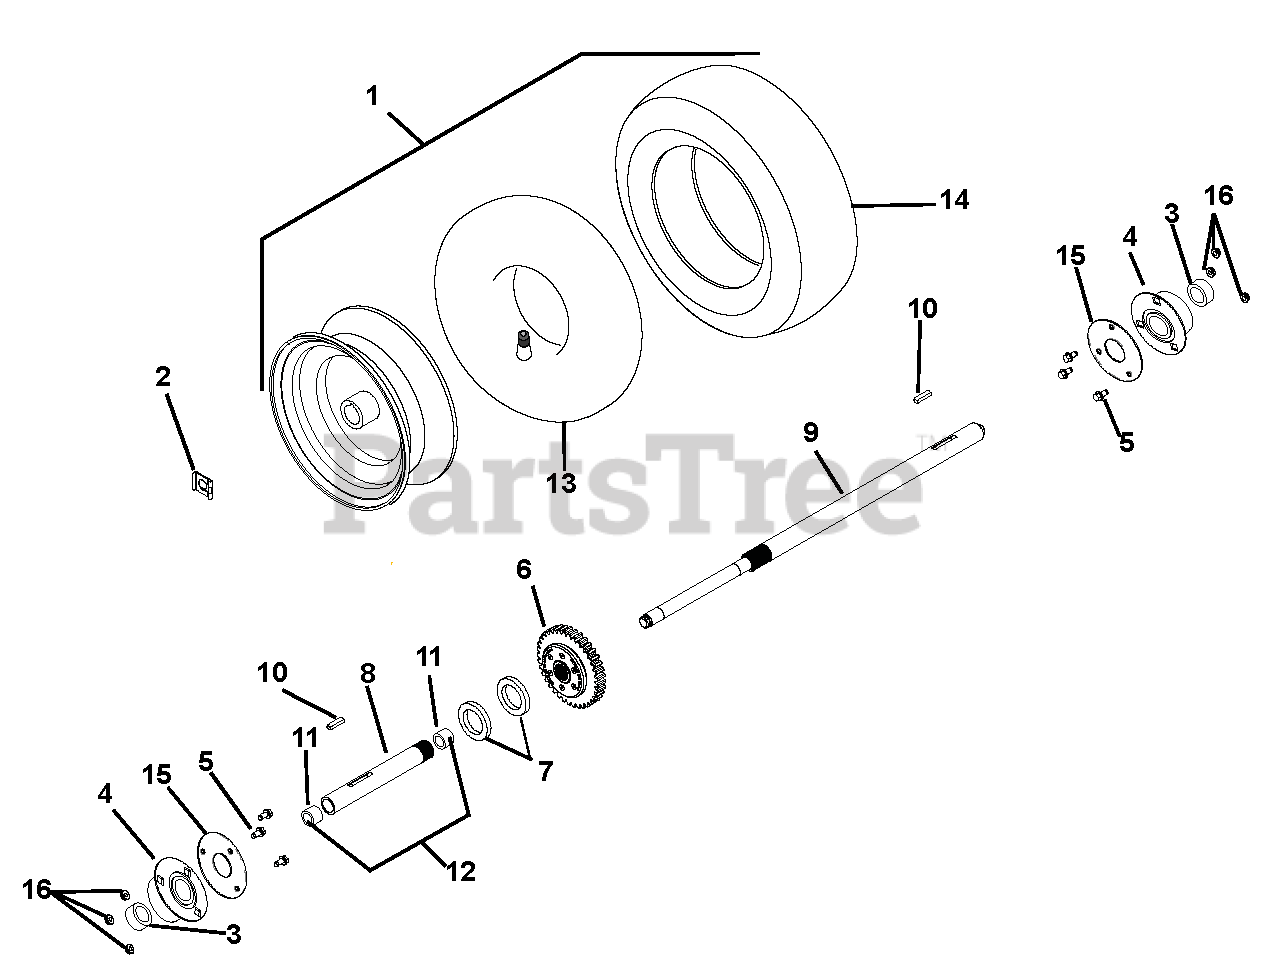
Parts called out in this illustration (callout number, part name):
1	TIRE/WHEEL, RH 16X6.50-8 DIFF
2	CLIP, SNAP .625 DIA
3	SPACER, PRO AXLE BEARING
4	BRG-FLG 1.003/1.000 3 BOLT
5	@BLT-HEX .25-20X.75 GR5 YWZC
6	DIFFERENTIAL, AUTOMATIC
7	WSHR-FL-STL- 1.062X2.0X.134 YZ
8	AXLE, SHORT-PRO AUTO DIFF
9	AXLE, LONG-PRO AUTO DIFF
10	KEY-RECT .25X.188X1.00
11	BSHG-SLV .706X.764X.75 BRZ
12	AXLE, SHORT-AUTO W/BUSHINGS
14	TIRE, 16X6.50-8 K478
15	PLATE, BEARING SPACER
16	@NUT-LK-TOP-FLG .25-20 YWZC
